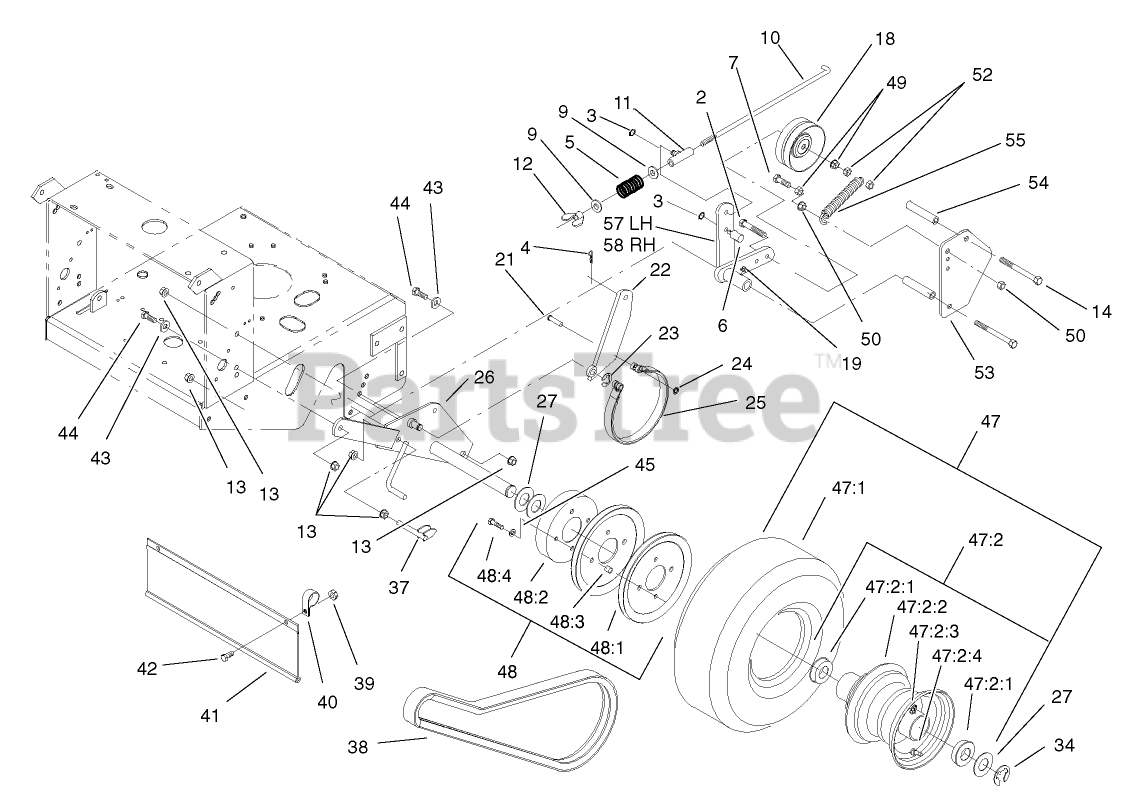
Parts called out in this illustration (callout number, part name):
2	SCREW-HH
3	RING-RETAINING
4	PIN-COTTER
5	SPRING-COMPRESSION
6	Swivel-Lever, Drive
7	SCREW-HH
9	WASHER-PLAIN
10	Linkage-Brake
11	SWIVEL-BRAKE
12	WINGNUT-NYLOCK
13	NUT-HHF, WHIZ
14	SCREW-HH
18	IDLER-WHEEL, DRIVE
19	FITTING-GREASE
21	PIN-CLEVIS
22	ARM-BRAKE
23	RING-RETAINING, EXTERNAL
24	NUT-PUSH
25	BAND-BRAKE
27	WASHER-SPACER
28	DRUM-BRAKE
29	SHEAVE-WHEEL, DRIVE
34	RING-SNAP
36	SCREW-HH
37	Scraper
38	V-BELT
39	NUT-LOCK, NI
40	CLAMP-R
41	SHIELD-TRAILING
42	SCREW-HH
43	WASHER-BELLEVILLE
44	SCREW-HH
45	WASHER
47	Wheel and Tire ASM
47:1	Tire-Turfmaster
47:2	WHEEL AND HUB ASM
47:2:1	BEARING-FLANGED
47:2:3	Fitting-Grease
47:2:4	Valve Stem and Cap
48	Drum and Sheave ASM
48:1	SHEAVE-WHEEL, DRIVE
48:2	DRUM-BRAKE
48:3	SPACER-SHEAVE, WHEEL
48:4	SCREW-HH
49	NUT-HHF, WHIZ
50	NUT-HF
52	NUT-LOCK, NI
53	Shield-Wheel, Drive
54	Spacer-Shield, Lower
55	SPRING-EXTENSION
57	Arm-Idler, LH
58	Arm-Idler, RH
